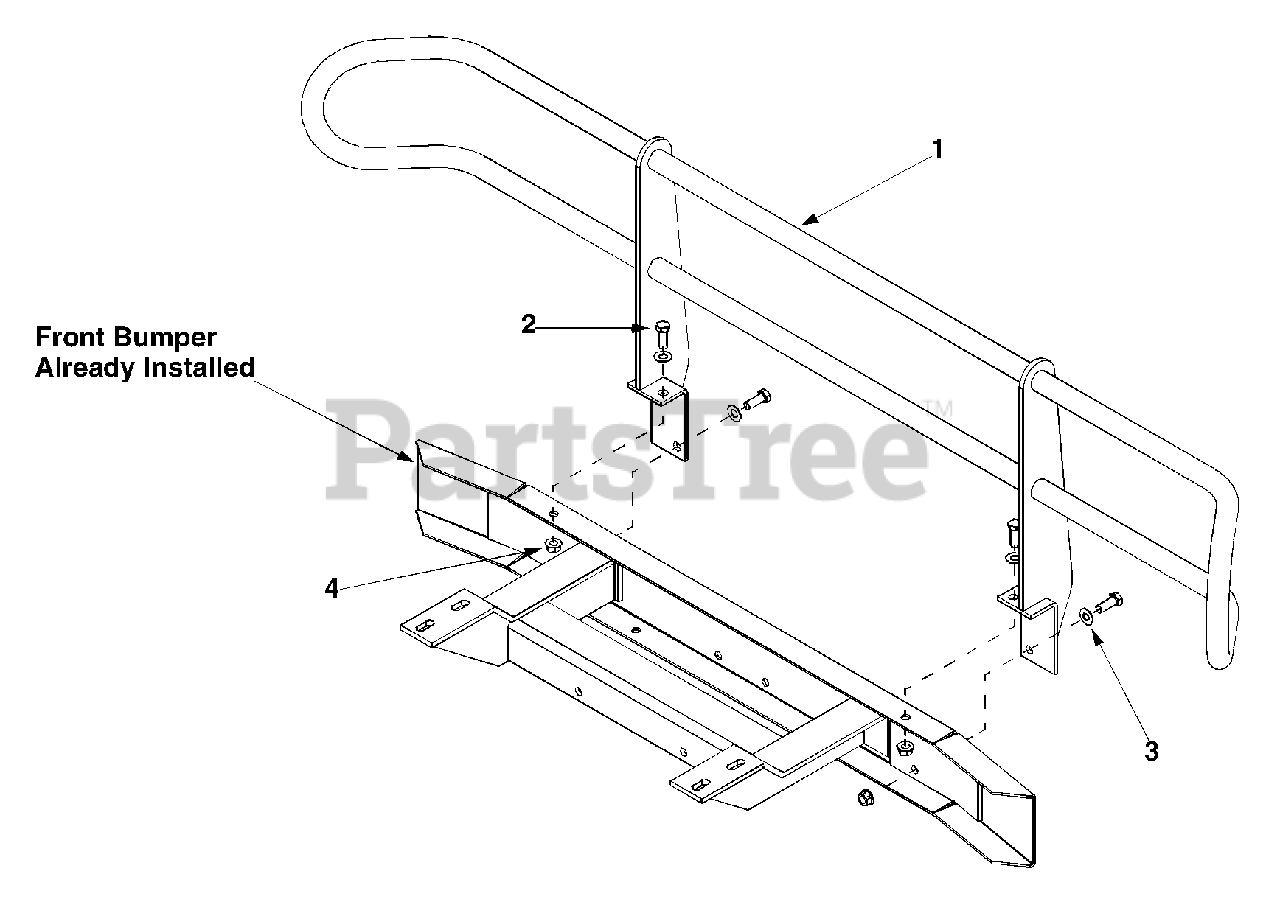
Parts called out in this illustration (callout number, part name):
1	Front Brush Guard
2	Hex Cap Screw 3/8-16 x 1.0
3	Flat Washer .406 ID x .812 OD
4	Flange Lock Nut 3/8-16
